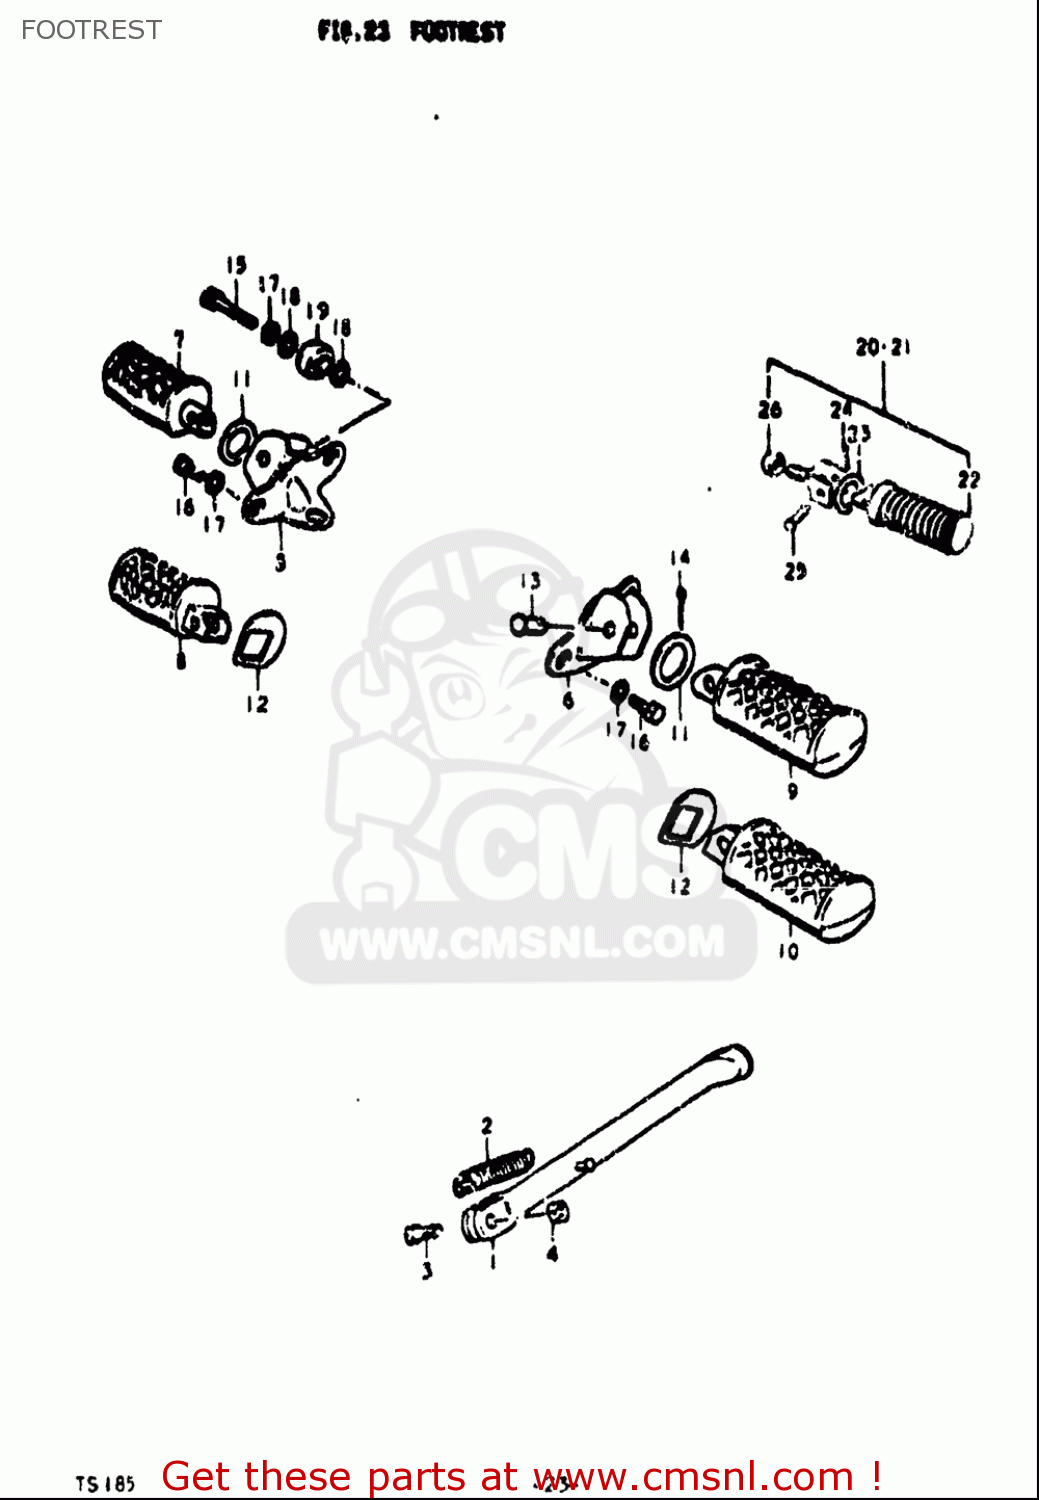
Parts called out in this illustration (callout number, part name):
2	SPRING
3	BOLT(10X30)
4	NUT
11	WASHER(22.5X38X1)
12	WASHER
13	PIN
14	PIN
15	BOLT
16	BOLT(8X14)
17	WASHER,LOCK
18	WASHER
21	FOOTREST ASSEMBLY,REAR
22	RUBBER,PILLION FOOTREST
23	WASHER(19.5X32X2)
24	PIN
25	PIN
26	NUT
